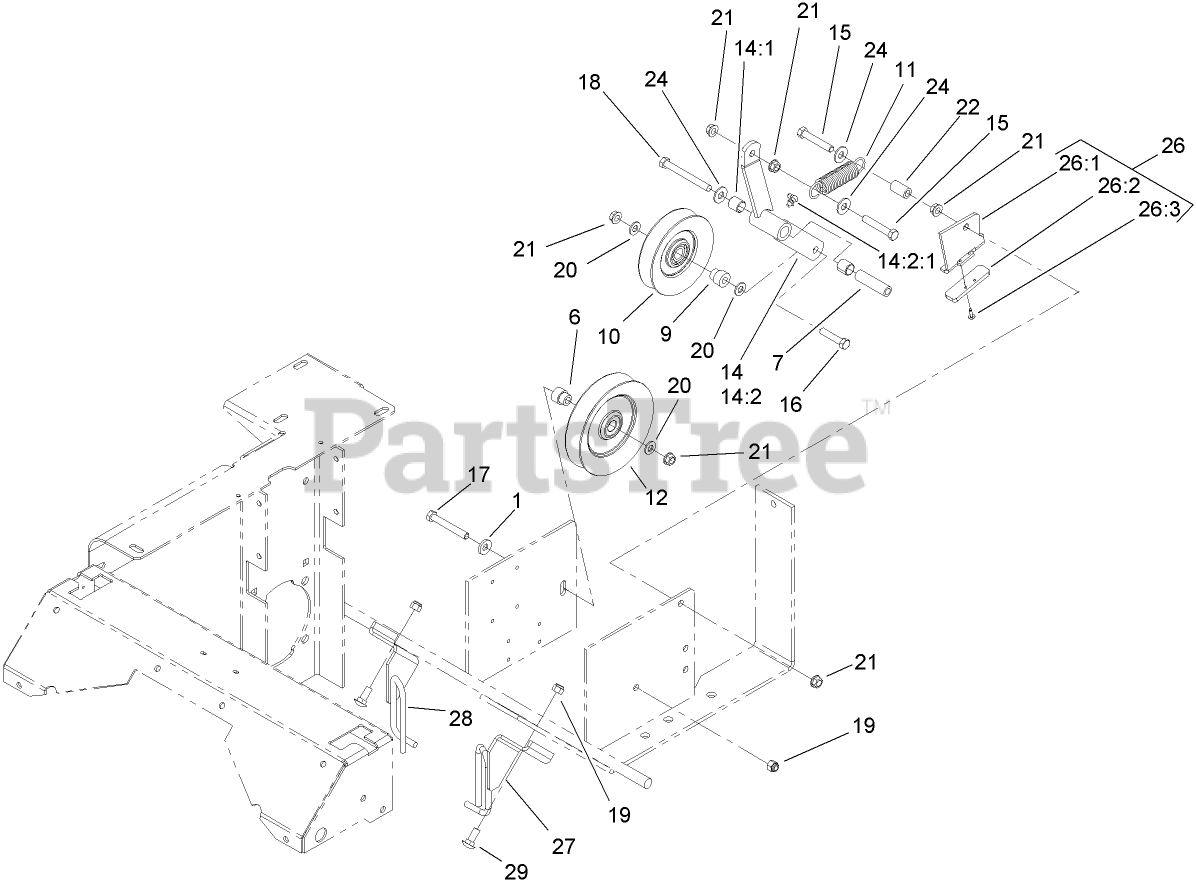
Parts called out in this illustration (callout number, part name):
1	WASHER-BELLEVILLE
6	Bushing-Idler
7	BUSHING-PIVOT, IDLER
9	BUSHING-IDLER
10	Idler
11	SPRING-EXTENSION
12	PULLEY-IDLER
14	Arm ASM
14:1	SLEEVE-BEARING
14:2	ARM-IDLER
14:2:1	FITTING-GREASE, 90 DEG
15	SCREW-HH
16	SCREW-HH
17	SCREW-HH
18	SCREW-HH
19	NUT-LOCK, NI
20	WASHER-FLAT
21	NUT-HHF, WHIZ
22	SPACER
24	WASHER-FLAT
26	Travel Limiter ASM
26:1	Plate-Limiter, Pulley
26:2	PAD-BUMPER
26:3	RIVET
27	GUIDE-BELT, LH
28	GUIDE-BELT, RH
29	BOLT-CARR
